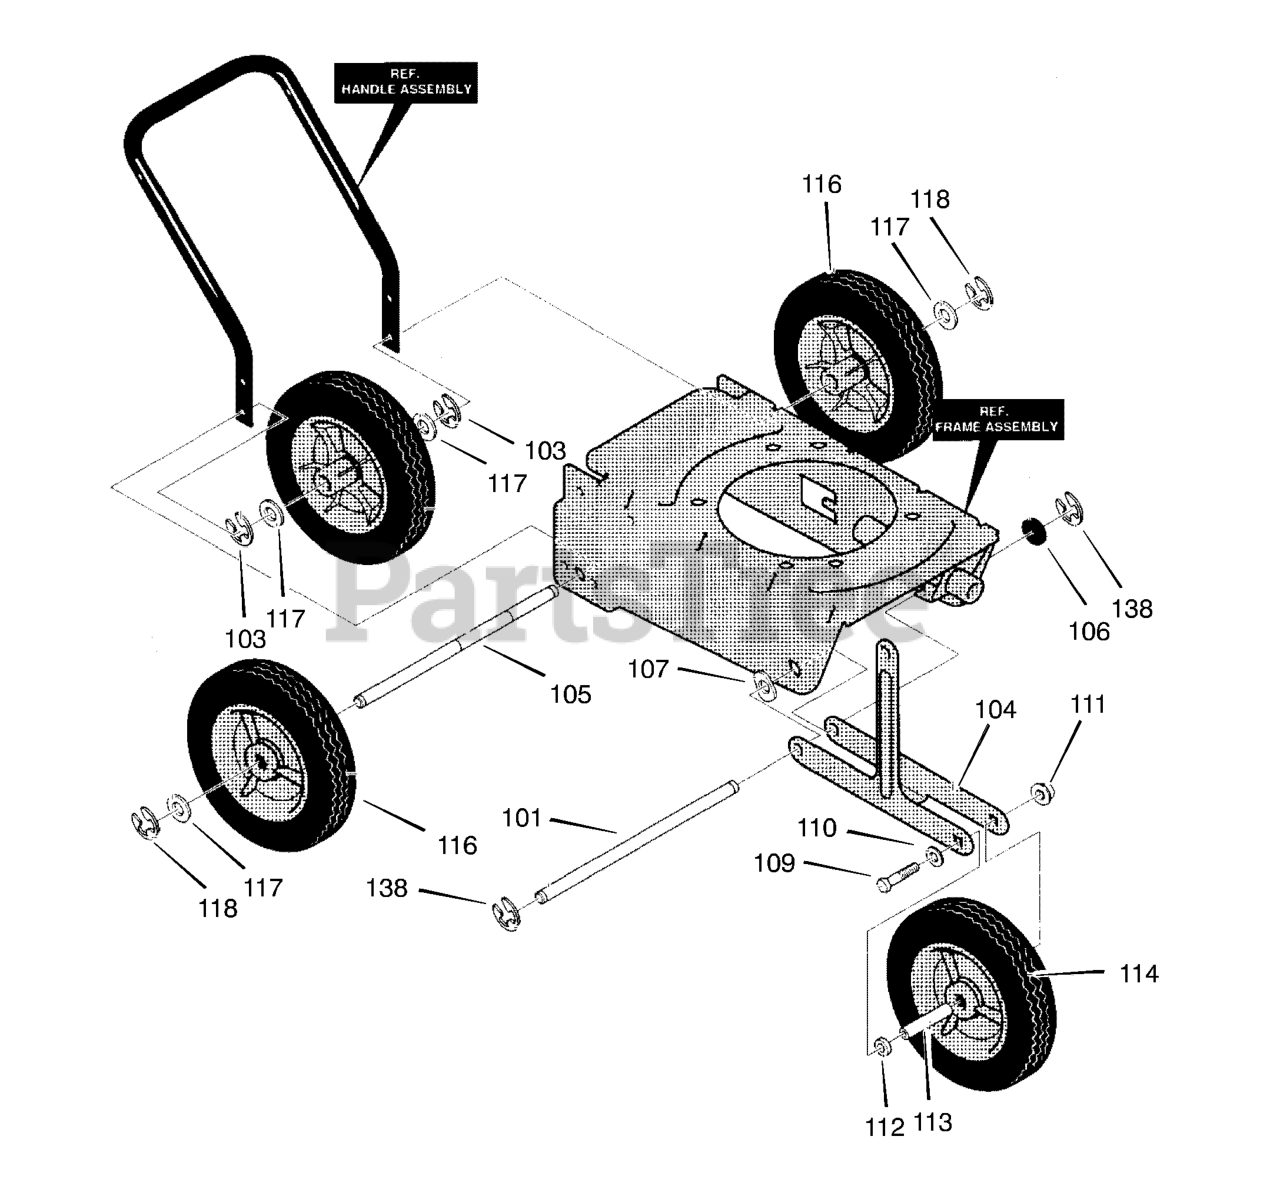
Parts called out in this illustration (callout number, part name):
101	Rod, Axle Front
103	E-Ring
104	Bracket, Curp Hop
105	Rod, Rear Axle
106	Washer, Flat
107	Washer, Spring
108	Tire & Rim
110	Washer, Flat
111	Nut, 5/16-18
112	Washer, Nylon
113	Spacer, Sleeve
114	Tire & Rim
116	Tire & Rim
117	Washer, Flat
118	E-Ring
138	E-Ring
